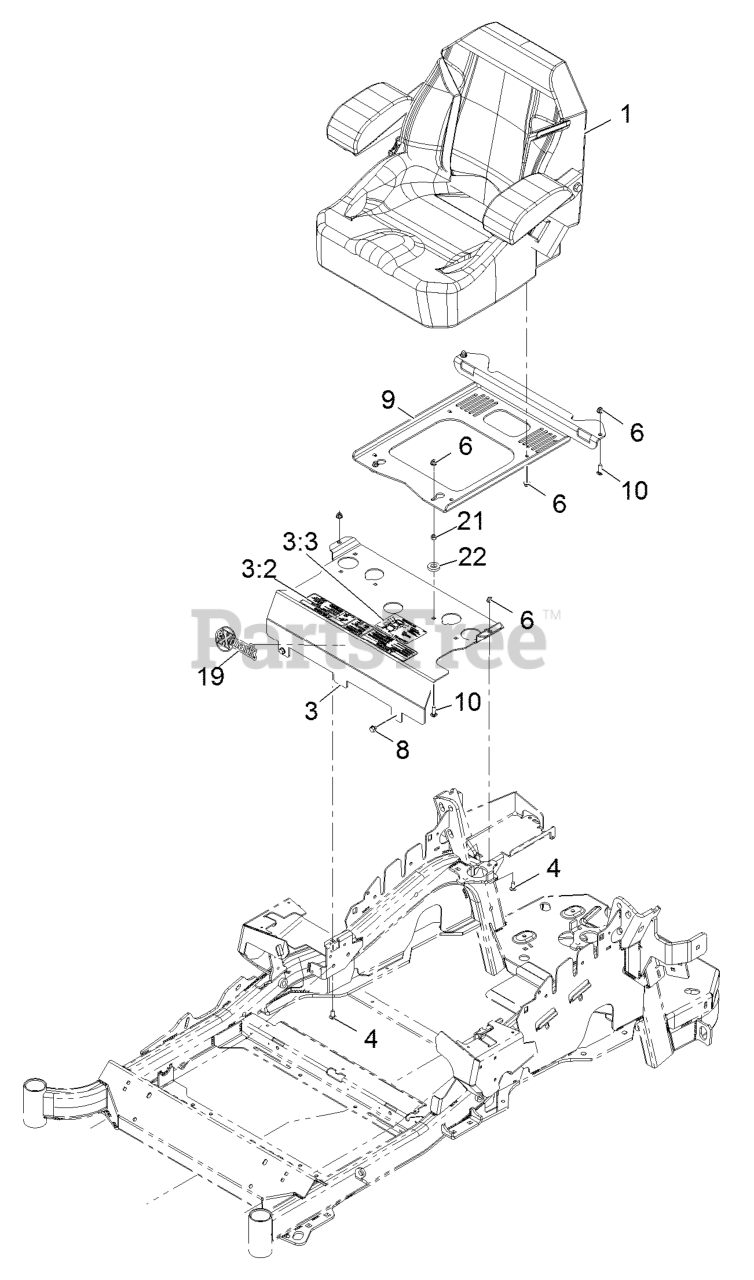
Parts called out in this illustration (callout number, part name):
3	MOUNT-SEAT
3:2	DECAL-CONSOLE
3:3	DECAL-SERVICE AID
4	SCREW-CARR
6	NUT-HF, NI
9	PLATE-SUPPORT, SEAT
10	SCREW-CARR
21	NUT-HEX
